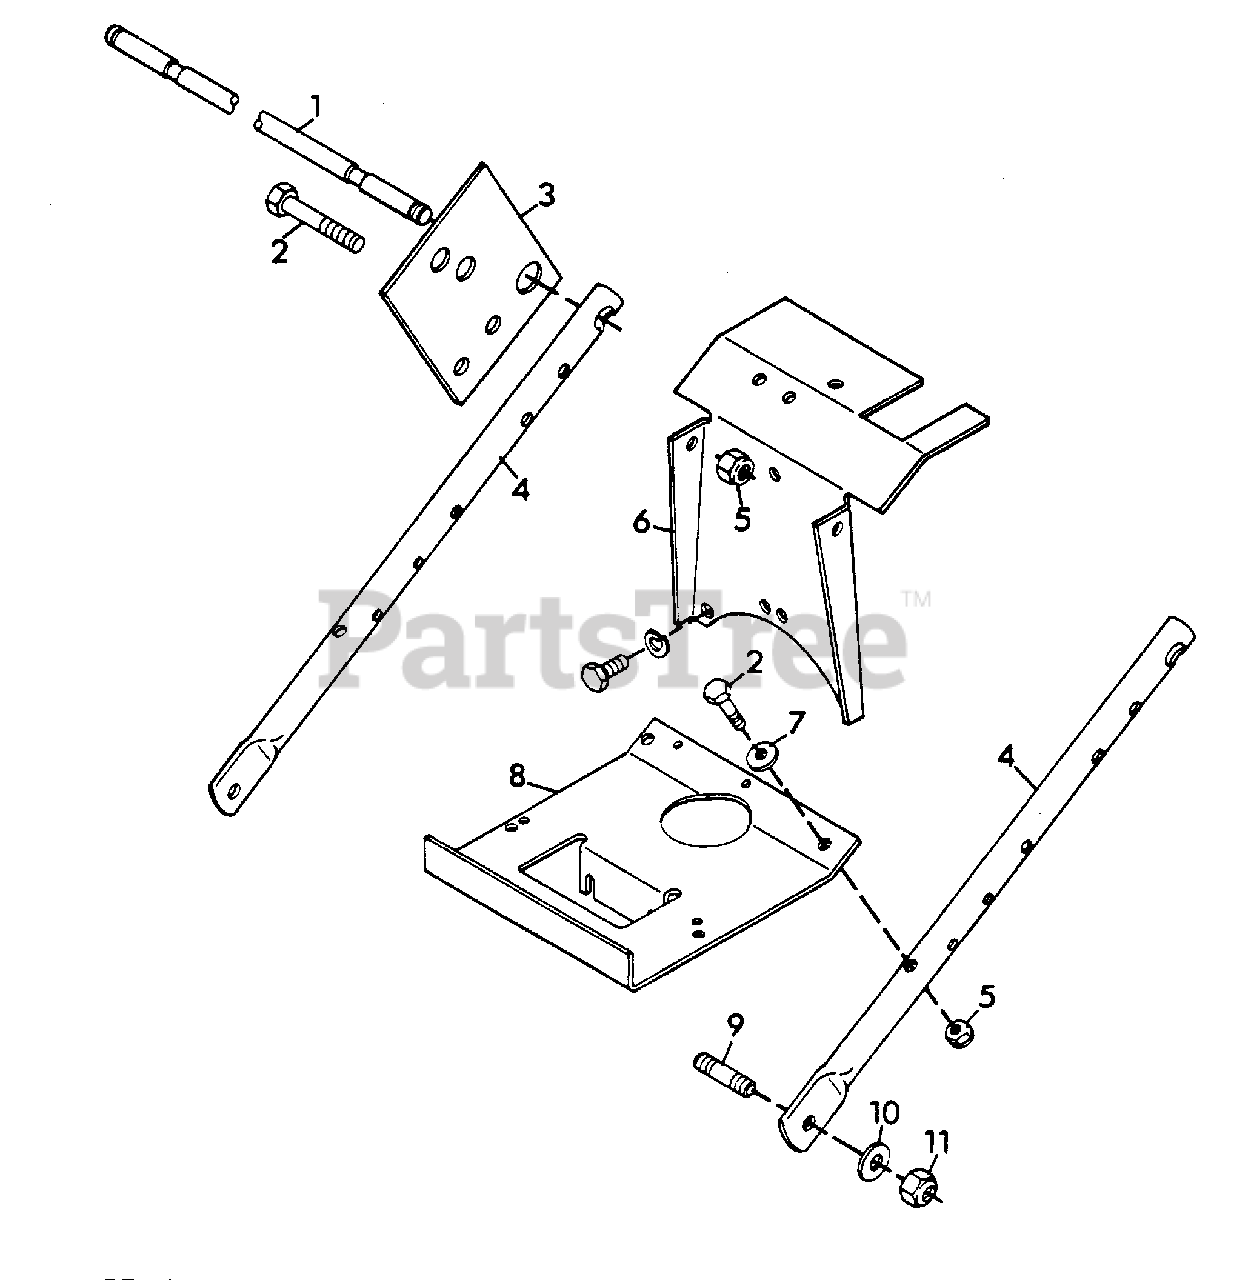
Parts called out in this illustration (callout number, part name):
1	SHAFT, CROSS
2	BOLT, HEX 3/8-16X2.25
3	BRACKET, INTERLOCK
4	TUBE, SUPPORT
5	NUT, LOCK 3/8-16
6	SHIELD, HEAT
7	WASHER, FLAT .406X.812X.065
8	BOX, BATTERY
9	STUD
10	WASHER, FLAT .531X1.062X.095
11	NUT, LOCK 1/2-13
